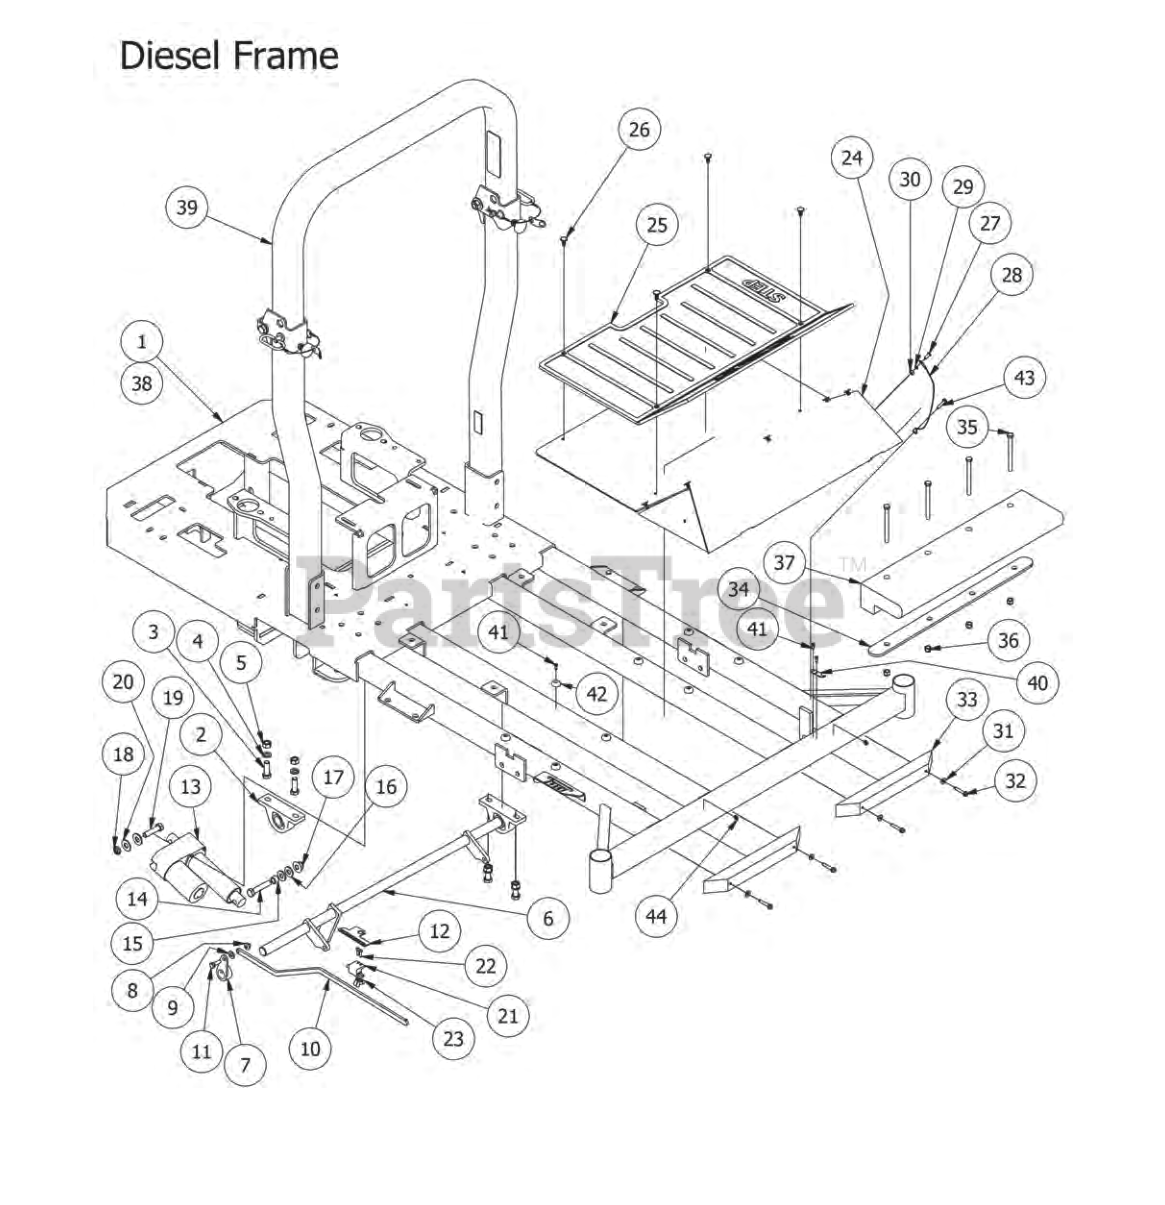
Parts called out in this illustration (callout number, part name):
1	Diesel 4cyl 72" Frame
2	pillow block 2bolt sealmaster
3	1/2" x 1 1/2" Hex Bolt
4	1/2" Lock Washer
5	1/2" Hex Nut
6	Actuator Bar
7	Height Indicator Lever
8	5/16" Flange Nut
9	360 ID Plastic Washer
10	Height Indicator Bar
11	5/16" x 1" Bolt
12	Deck Stop Bracket 2008
14	1/2" x 2 1/2" Hex Bolt
15	1/2 x 1/2 Spacer
16	.505 Nylon Spacer
17	1/2-13 Nylon Flange Nut-Orange
18	1/2" Nylcock Nut (1/2 Jam)
19	1/2" x 2" Hex Bolt
20	1/2" Washer (Grade 8)
21	Deck Stop Switch
22	1024 x 1" Allenhead Bolt
23	M6x1.0x20MM 8.8 Hex Bolts Zinc
24	Floor Panel
25	AOS Floor Mat
26	Ratchet Fastener-Floorboard
27	1/4" x 5/8" Buttonhead Bolt
28	Floor board Cable W/ Swivel Ends
29	1/4" Lock Washer
30	1/4" Hex Nut
31	1/4" Flat Washer
32	1/4" x 1 1/2" Self Tapping Screw
33	14" Rubber Bumper
34	Diesel Weight Bar Bracket
35	3/8" x 4 1/2" Bolt
36	3/8 Nylock Nut
37	58lb Diesel Weight
38	Diesel 4cyl 61" Frame Suspension
39	2 X 3 ROPS Fits All 2012 Diesel Models
40	2006 Floor Panel Stop
41	#10 x 1/2" Self Taping Screw
42	Button Bumper
43	1/4 x 1 Hex Head tek screw
44	Brass Washer for Weld-On Hinge
